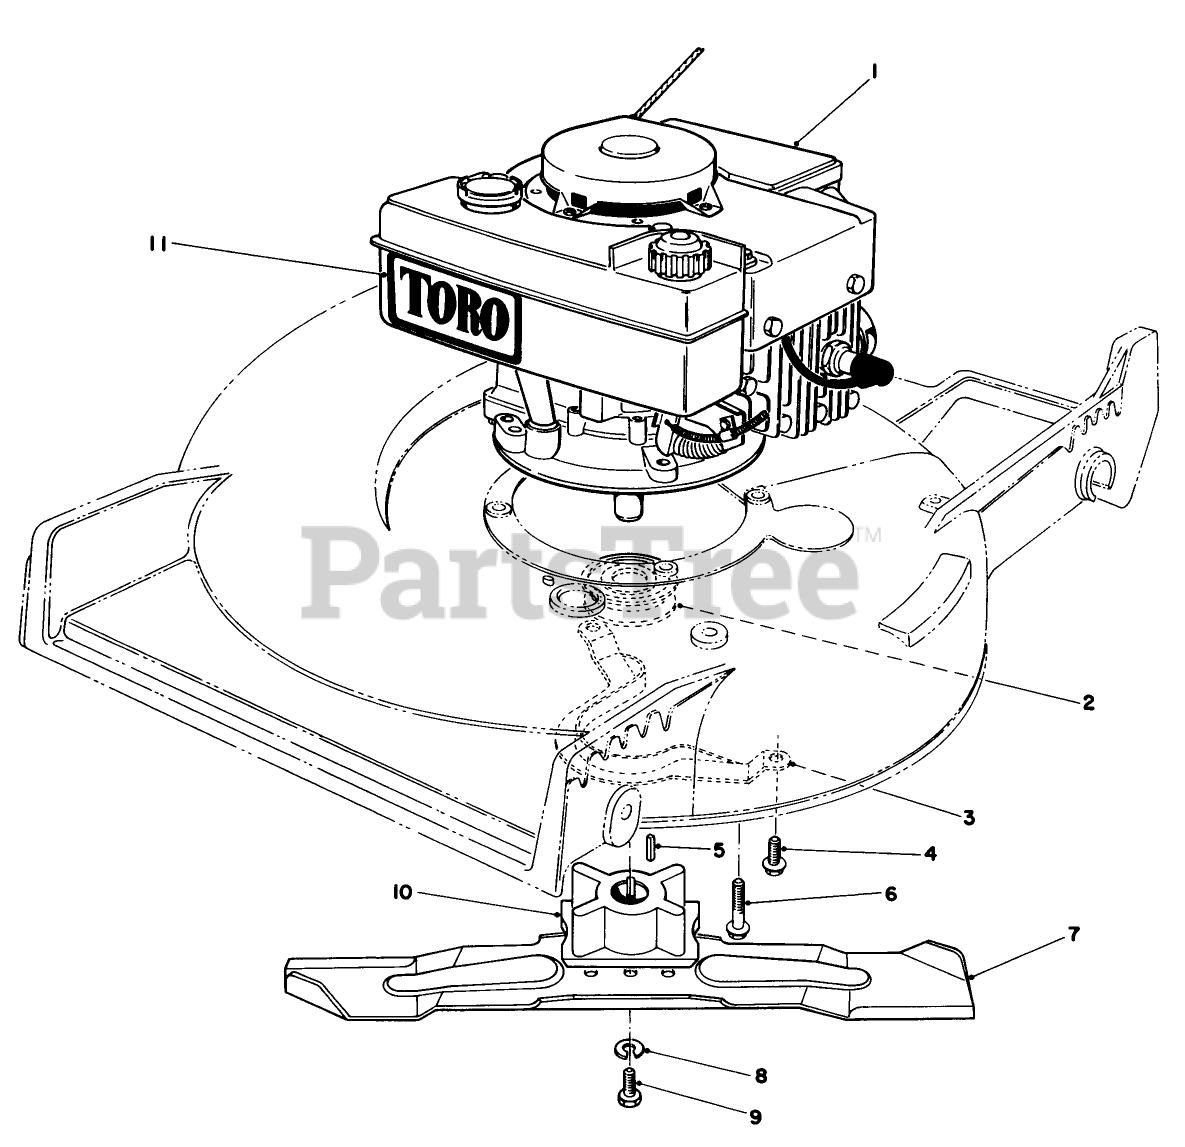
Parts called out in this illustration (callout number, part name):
1	Engine
2	Pulley
3	BELT GUIDE
4	Screw
5	KEY-SQUARE
6	Screw-Thread Forming
7	BLADE-21in
8	SCREW-BLADE
9	WASHER-LOCK
10	BLADE RETAINER(DEEP)
11	Decal Tow
